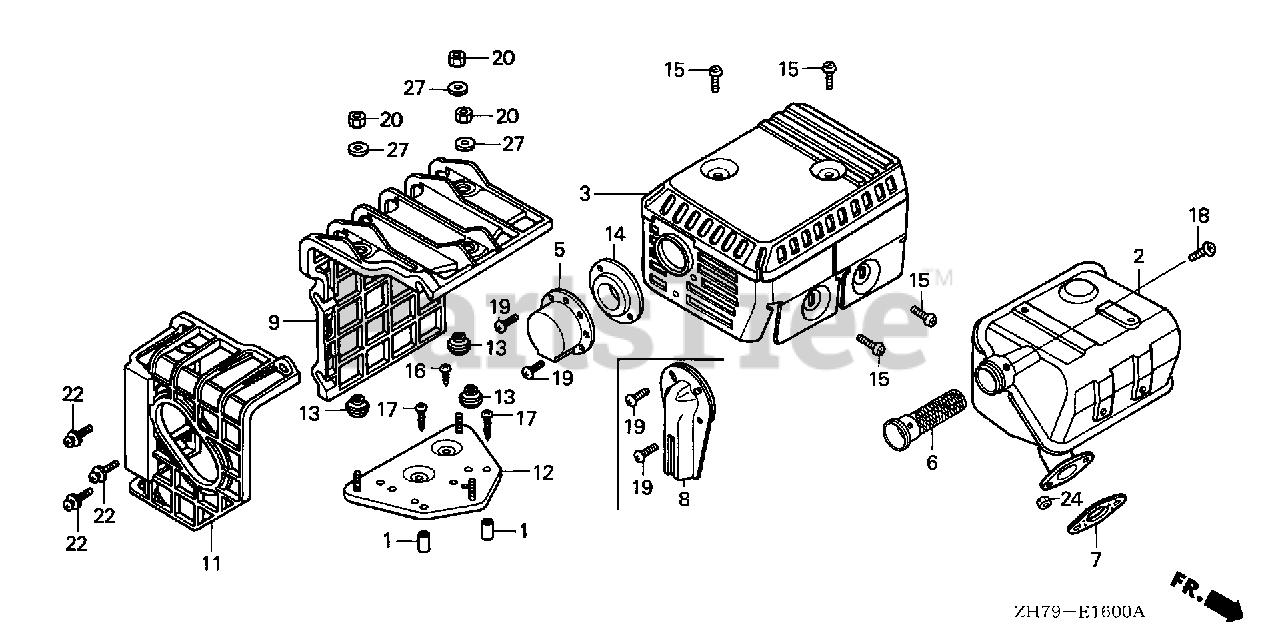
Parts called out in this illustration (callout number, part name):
2	MUFFLER
3	PROTECTOR, MUFFLER
6	ARRESTER, SPARK
7	GASKET, MUFFLER
15	SCREW, TAPPING (5X8)
18	SCREW, TAPPING (4X6)
24	NUT, HEX. (8MM)
